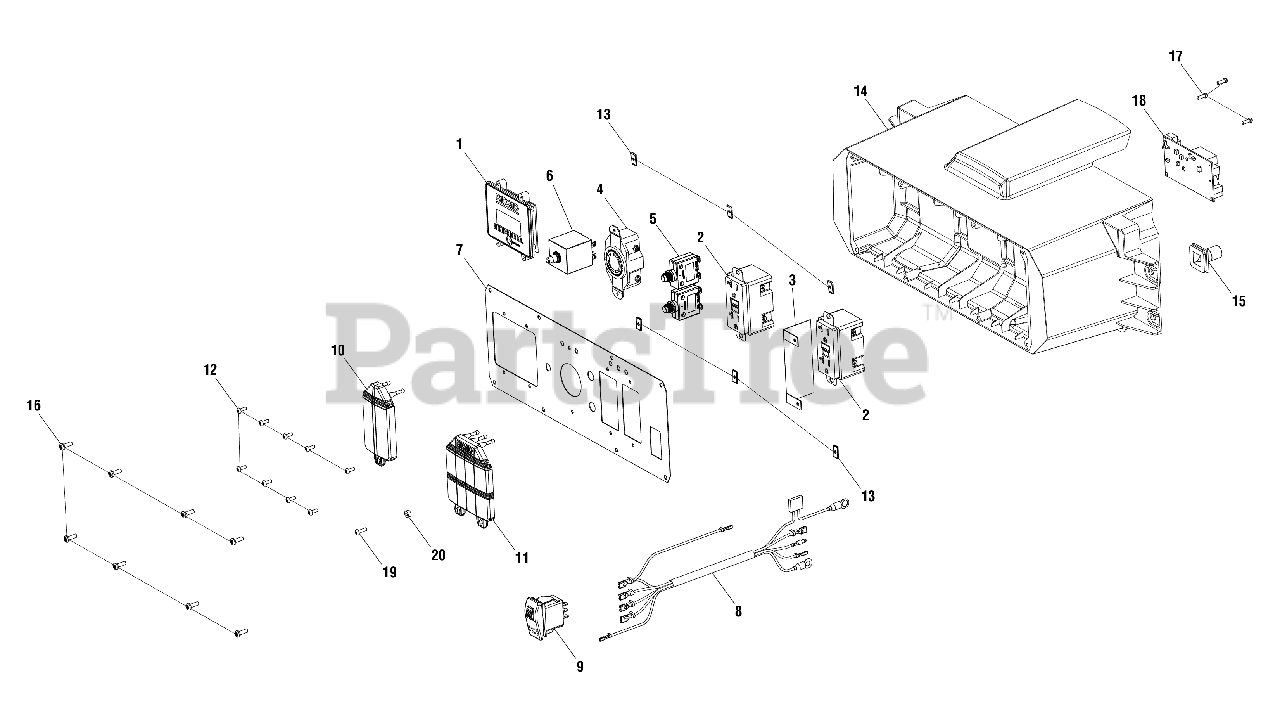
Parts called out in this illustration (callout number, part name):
1	GENSMART 120/240V ENGLISH/FRENCH
2	Duplex GFCI Receptacle (120 Volt)
3	INSULATOR
4	Twist Lock Receptacle (120/240 Volt, 30 Amp, L14-30R)
5	Circuit Breaker (20 Amp)
6	CIRCUIT BREAKER, 30AMP 2 POLE SCREW TYPE
7	ELECTRICAL FACEPLATE, RD9C7001P
8	E-START HARNESS, RD9C7001P
9	Start Switch w/Lock
10	RAIN SHIELD, 30 AMP TWISTLOCK
11	RAIN SHIELD, DUEL GFCI
12	Screw (#6-20 x 3/8 in., T15 Torx Pan Hd.)
13	NUT, SPEED #6-18
14	WRAPPER BOX W/ HOLE, RIGID
15	Rubber Grommet
16	Screw (#8-18 x 1/2 in., T20 Torx Pan Hd.)
17	Screw (6-20 x 3/8 in., Phillips Pan Hd.)
18	Battery Charger
19	SCREW, #6-10 X 0.5 TYPE B ZINC TORX HD
20	SPACER 4mm
